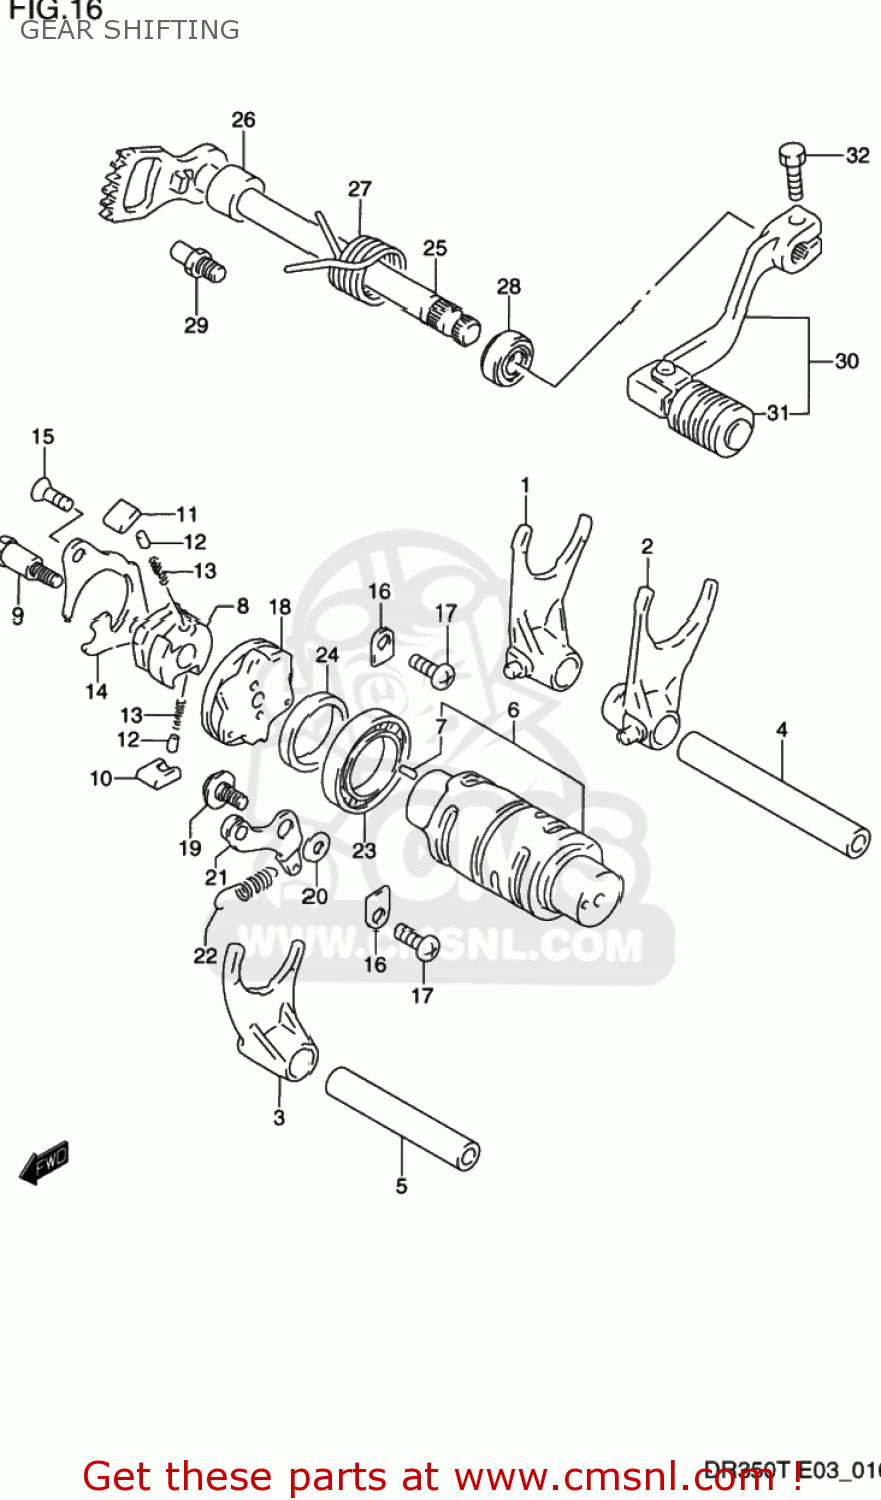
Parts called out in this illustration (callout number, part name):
1	FORK,GEAR SHIFT NO.1
2	FORK,GEAR SHIFT NO.2
3	FORK,GEAR SHIFT NO.3
4	SHAFT,GEAR SHIFT FORK
5	SHAFT,GEAR SHIFT FORK(L:70)
6	CAM,GEAR SHIFT
7	PIN
8	GEAR,GEARSHIFT CAM DRIVE
9	PIN,SHIFT CAM DRIVEN GEAR
10	PAWL,GEAR SHIFT NO.1
11	PAWL,GEAR SHIFT NO.2
12	PIN(5X8)
13	SPRING
14	LIFTER,GEAR SHIFT PAWL
15	SCREW
16	RETAINER
17	SCREW
18	PLATE,GEAR SHIFT CAM
19	BOLT(6X14.3)
20	WASHER
21	STOPPER,GEAR SHIFT CAM
22	SPRING
23	BEARING
24	WASHER(25X32X5.3)
25	SHAFT,GEAR SHIFT
26	SPACER(12X20X15.3)
27	SPRING
28	OIL SEAL
29	STOPPER,GEAR SHIFT ARM
30	LEVER ASSY,GEAR SHIFT
31	RUBBER,GEAR SHIFT PEDAL
32	BOLT
